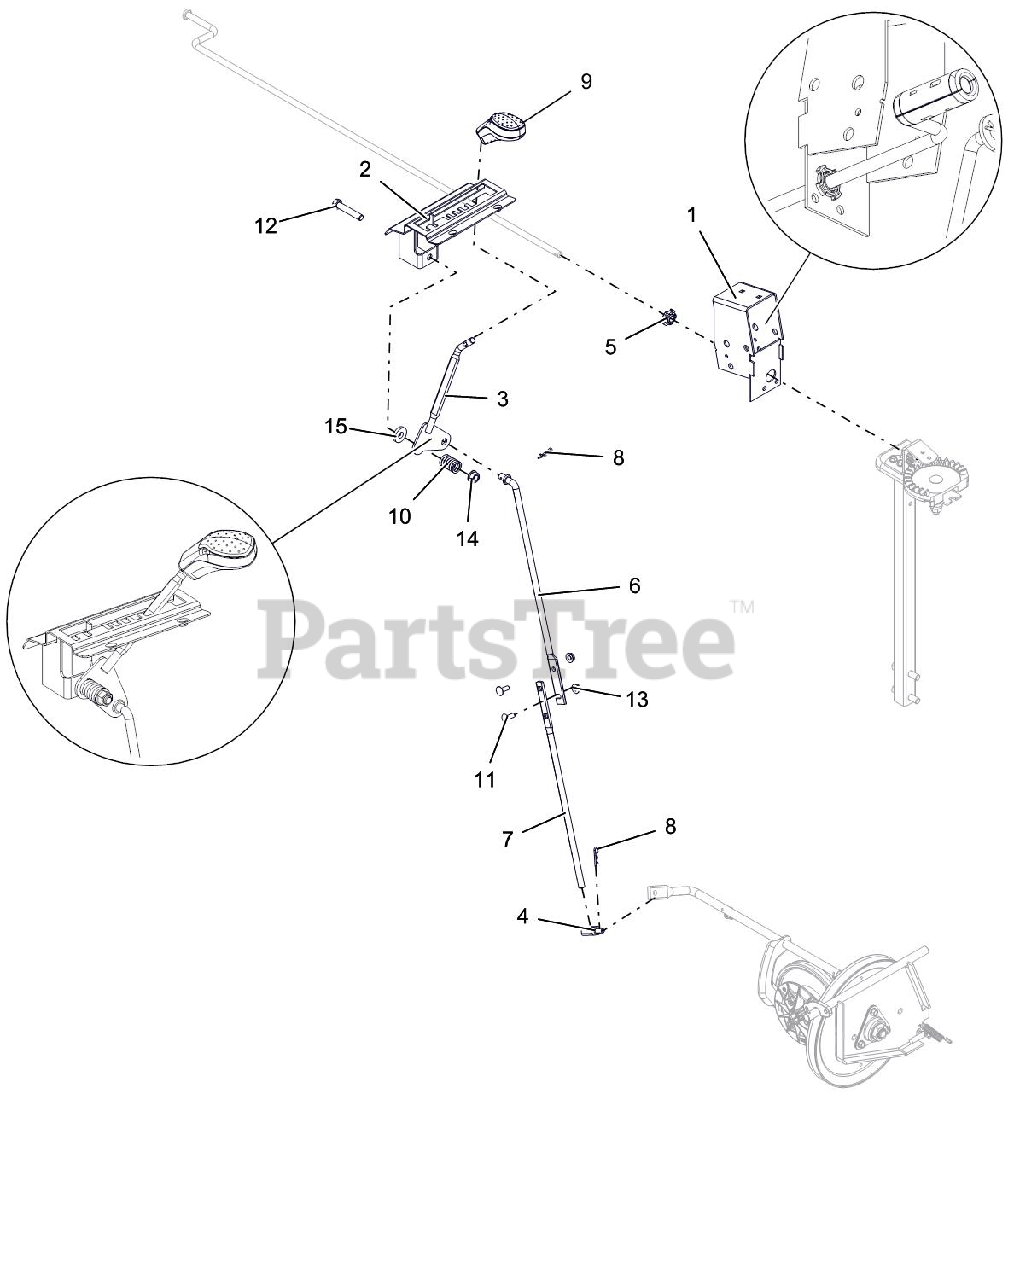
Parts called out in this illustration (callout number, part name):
1	WELDMENT, BRACKET INTERLOCK
2	WELDMENT, DETENT PLATE-COMPACT
3	LEVER, CONTROL-SHIFT(WELDMENT)
4	PIVOT,SHIFT ROD .375-16(TRUNN)
5	CRANK BUSHING, NYLON CHUTE BK
6	ROD, SHIFT - UPPER
7	ROD, SHIFT - LOWER(SMALL DASH)
8	PIN-HAIR INT .08X.18X1.18 YWZC
9	KNOB, CONTROL, DASH
10	SG-COMP .125X.781X1.250
11	@BLT-RDHDSQNK .25-20X.75 G5YZ
12	@BLT-HEX .38-16X2.00 GR5 YWZC
13	@NUT-LK-CTR-FLG .25-20 YWZC
14	@NUT-LK-TOP-FLG .38-16 YWZC
15	WSHR-FL-STL .406X1.00X.188 YWZ
